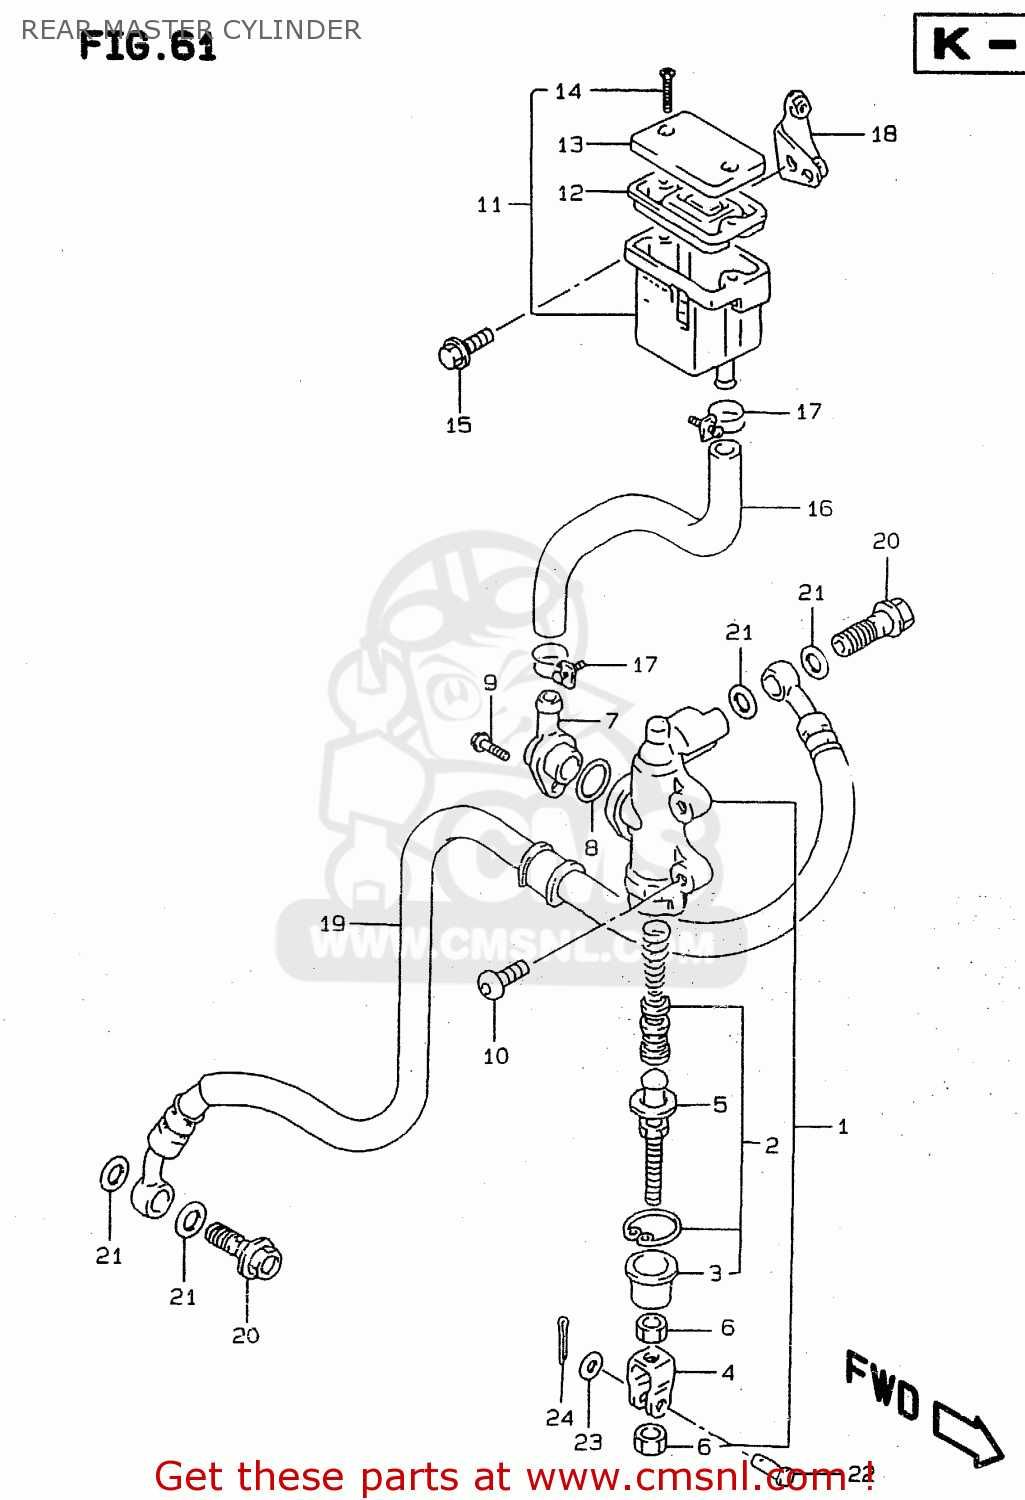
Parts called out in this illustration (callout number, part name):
1	CYLINDER ASSY,RR MASTER
2	PISTON/CUP SET
3	BOOT
4	YOKE
5	ROD,PUSH
6	NUT
7	CONNECTOR
8	O RING
9	SCREW
10	BOLT 8X20
11	TANK ASSY,RESERVOIR
12	DIAPHRAGM
13	CAP
14	SCREW
15	BOLT
16	HOSE,RESERVOIR TANK
17	CLIP
18	PLATE COMP,RESERVOIR T
19	HOSE,RR BRAKE
20	BOLT UNION
21	WASHER(10X15X1.5)
22	PIN
23	WASHER
24	PIN
